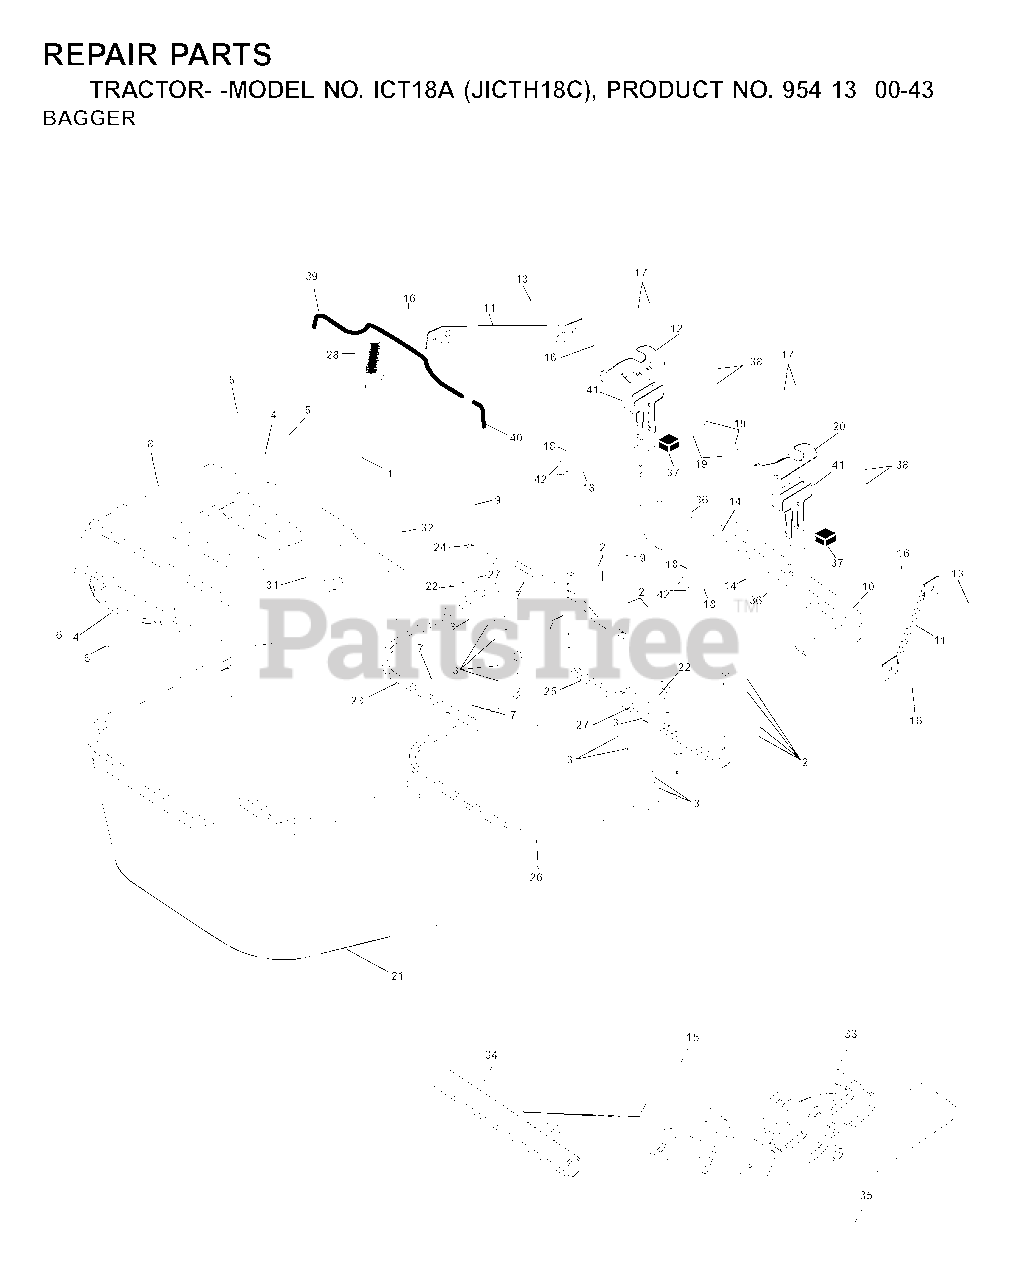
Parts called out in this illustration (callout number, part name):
1	TUBE HANDLE BAGGER
3	NUT T
5	SCREW.PAN.HEAD
10	TUBE
11	BRACKET
15	RETAINER-SPRNG RB
16	NUT LOCK FLG 3/8-16 UNC
17	BOLT
18	WASHER M
19	NUT LOCK HEX FLANGE 5/16-18
20	BRACKET
21	BAG
22	BRACKET
23	TUBE
24	TUBE
26	TUBE
31	RETAINER M
32	RIVET,DRILLED
33	MULCH PLUG, CTH150
35	PIN
36	WASHER
38	BOLT.5/16-18X2.5
39	TRIM
40	TRIM
41	BRKT, BAGGER
42	NUT.71038.31-18.HEX.NYLOCK
